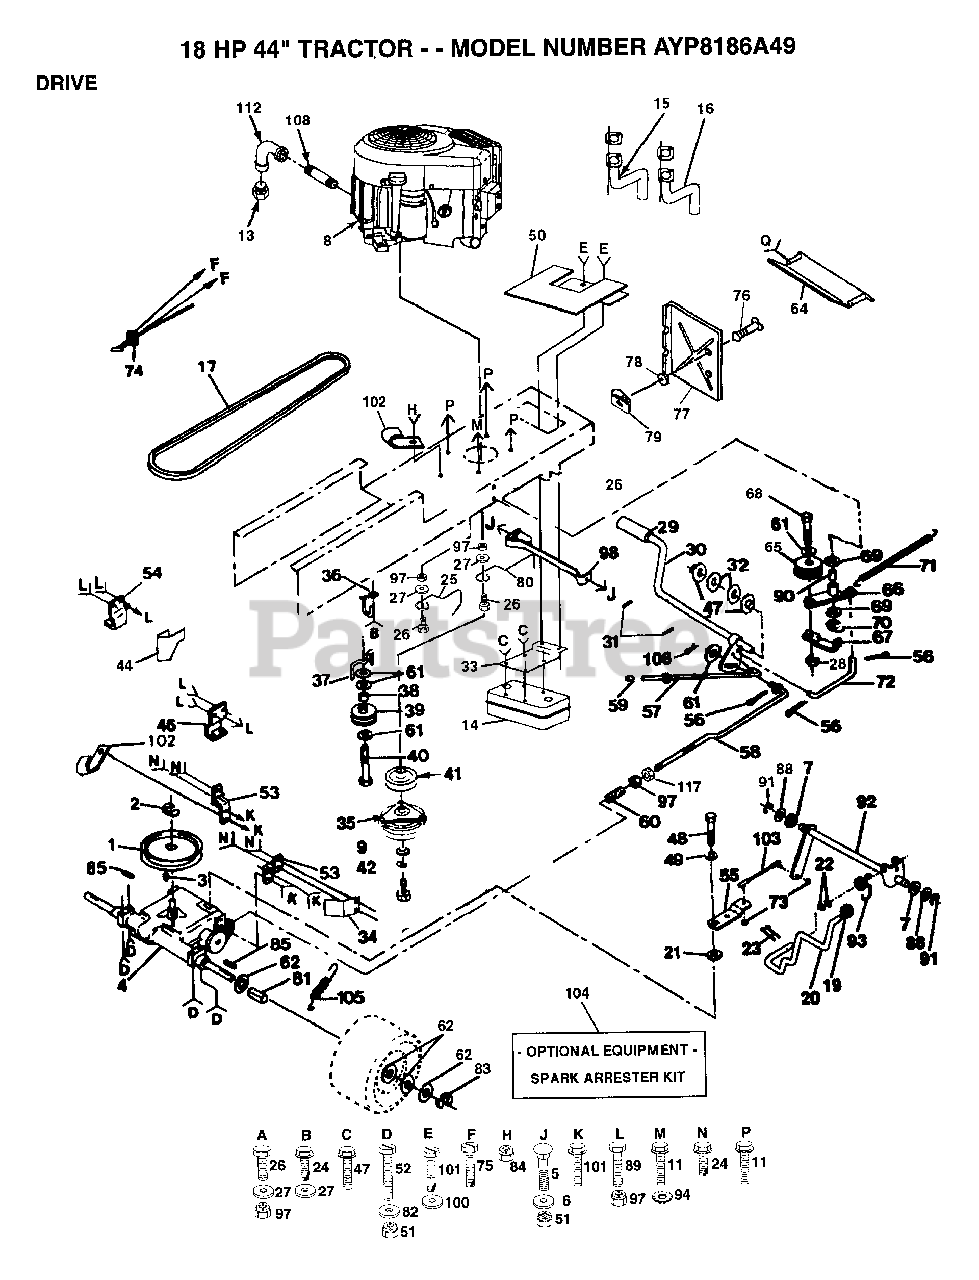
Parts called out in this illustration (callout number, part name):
1	PULLEY TRANSAXLE
2	RING
4	TRANSAX. PRLES.
5	BOLT
6	WASHER T
7	BUSHING
9	WASHER
11	SCREW LT
15	TUBE ASSY EXH LH
16	TUBE ASSY EXH RH
17	BELT.GRDRV.94.75
19	KNOB T (1/2-HOLE)
21	WASH-SHFT PLT LT
22	WASHER
23	PIN COTTER 1/8
24	SCREW
25	KEEPER BELT ENGLH
26	BOLT
27	WASHER
29	PEDAL COVER T
32	WASHER LT
33	BRACKET MUFFLER
34	"KEEPER,BELT RH"
36	KEEPER BELT CNTSP
37	BELT KEEPER LT
38	SPACER T
39	PULLEY.IDLER.FLAT
40	BOLT
41	PULLEY ENGINE
42	LOCKWASHER
44	KEEPER BELT LH
45	SCREW ST
46	BRKT TRANS RH
47	NYLON BEARING
49	WASHER PM
50	SHIELD HEAT LT
52	BOLT HEX
53	STRAP TORQUE
54	BRKT TRANS LH
55	"ARM,SHIFT"
56	COTTER PIN
57	BRAKE PARK ROD
58	ROD BRAKE
60	"SPRING,ROD BRAKE"
61	WASHER
62	WASHER
63	WASHER
64	HEAT SHIELD
66	ARM IDLER
67	RETAIN BELT
69	WASHER LT
70	KLIP RING
71	"SPRING, RETURN LT"
72	"LINK, CLUTCH T"
73	NUT 1/4-28
75	SCREW LT
76	STUD.1/4.TURN
77	HEAT SHIELD
78	RETAINER LT
79	RECEPTACLE LT
80	"KEEPER,BLT ENG LT"
81	SPACER HYT
82	WASHER M
83	E RING HYT
84	NUT
85	SQ KEY STD
88	WASHER D
90	"LY, BEARING"
91	KLIP RING
92	"SHAFT,SHIFTER"
93	"SPRING,TORSION"
94	LOCKWASHER
97	NUT
98	BRACKET.ASM.MTG
100	WASHER
101	SCREW
102	CLIP T
103	"ROD,TIE "
106	RETAINER M
108	PIPE NIPPLE LT
112	ELBOW
116	SCREW
117	NUT
